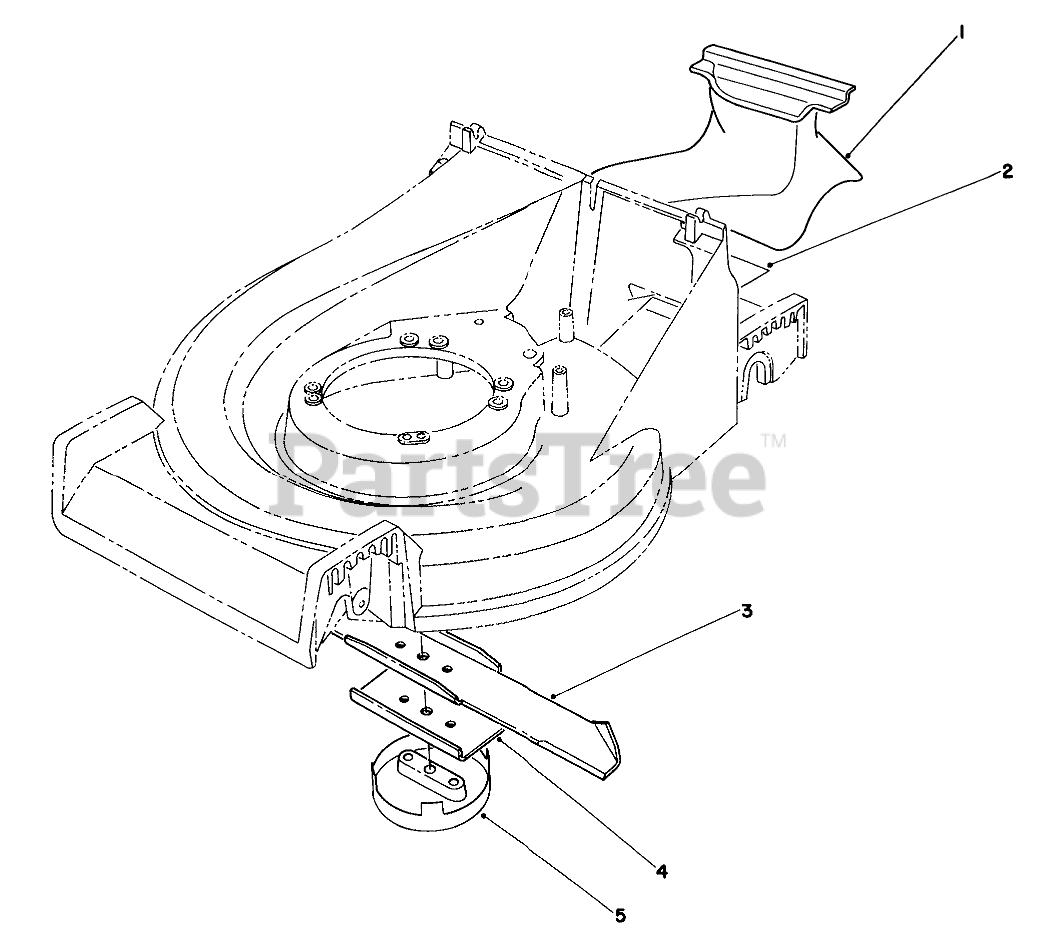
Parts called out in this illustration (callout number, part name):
1	RECYCLER PLUG
2	DECAL - MULCHER KIT
3	BLADE-21in
4	Stiffener
5	CUP-SCALP, ANTI
